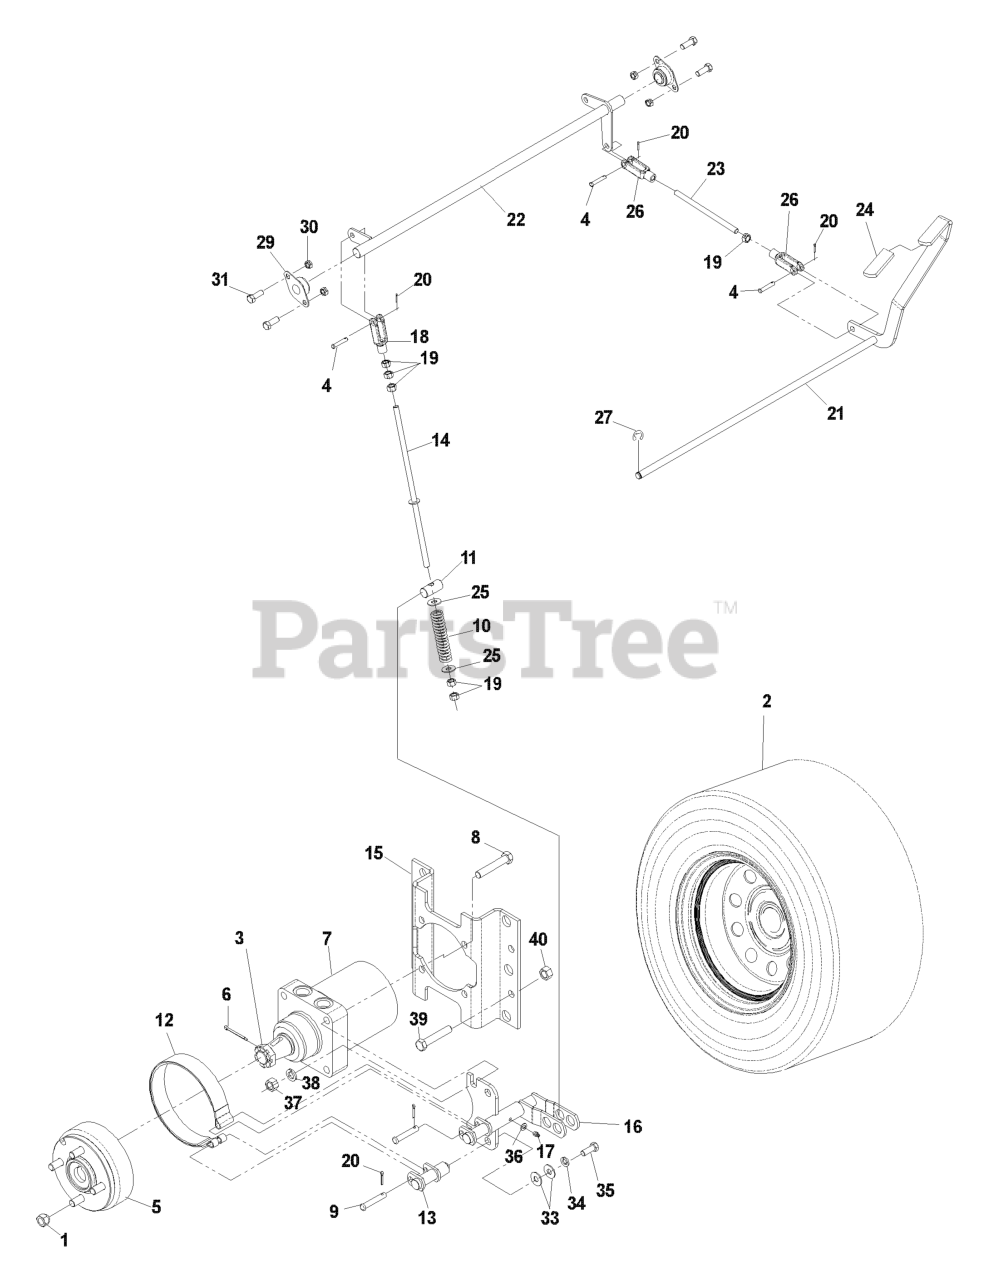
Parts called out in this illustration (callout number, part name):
1	LUG NUT 1/2F
2	WHEEL/TIRE.ASM.23X8.5-12.GREY
2	TIRE - 23X8.5-12
2	RIM.12X7.GRAY.+1".OFFSET.ZTR
2	VALVE STEM TR-412
2	WHEEL/TIRE.ASM.23X10.5-12.GREY
2	TIRE.TURF.MASTER.23X10.5-12
2	RIM 0 OFFSET 8.5" WIDE
3	NUT 3/4-16 HEX SLTD GR5 ZD
4	CLEVIS PIN 3/8 X 1 1/8
5	HUB W/BRAKE DRUM
6	PIN COTTER 4MM X 45MM
7	MB WHEEL MOTOR
8	HCS 1/2C X 2 3/4
9	CLEVIS PIN
10	COMPRESSION SPRING
11	TRUNION PIN
12	BRAKE BAND
13	BRAKE BAND SUPPORT
15	MOTOR STANDOFF
16	BRAKE WLDMNT
17	ZERK
18	YOKE-3/8-24 PLTD
20	RP_COTTER PIN 1/8 X 3/4
21	BRAKE LEVER WLDMNT
22	BRAKE CROSS SHAFT
23	LINKAGE - SHORT
24	GRIP, PARK BRAKE
25	WASHER, 7/16 DISC SPRING
26	YOKE-3/8-24 PLTD
27	E-RING 1/2 (2 2)
29	FLANGE BEARING
30	NUT 3/8-16 NYLOC
31	HCS 3/8-16X1.GRD.5.ZD
32	RP_COTTER PIN 1/8 X 3/4
33	WASHER 3/8 FLAT
34	SLW 3/8 STD
35	HEX BOLT 3/8 X 1"
37	NUT HEX 1/2
38	WASHER 1/2" SPLIT LOCK
39	HCS 1/2C X 1 1/4 SERRATED HEAD
40	NUT 1/2-13 HEX NYLOC ZD
